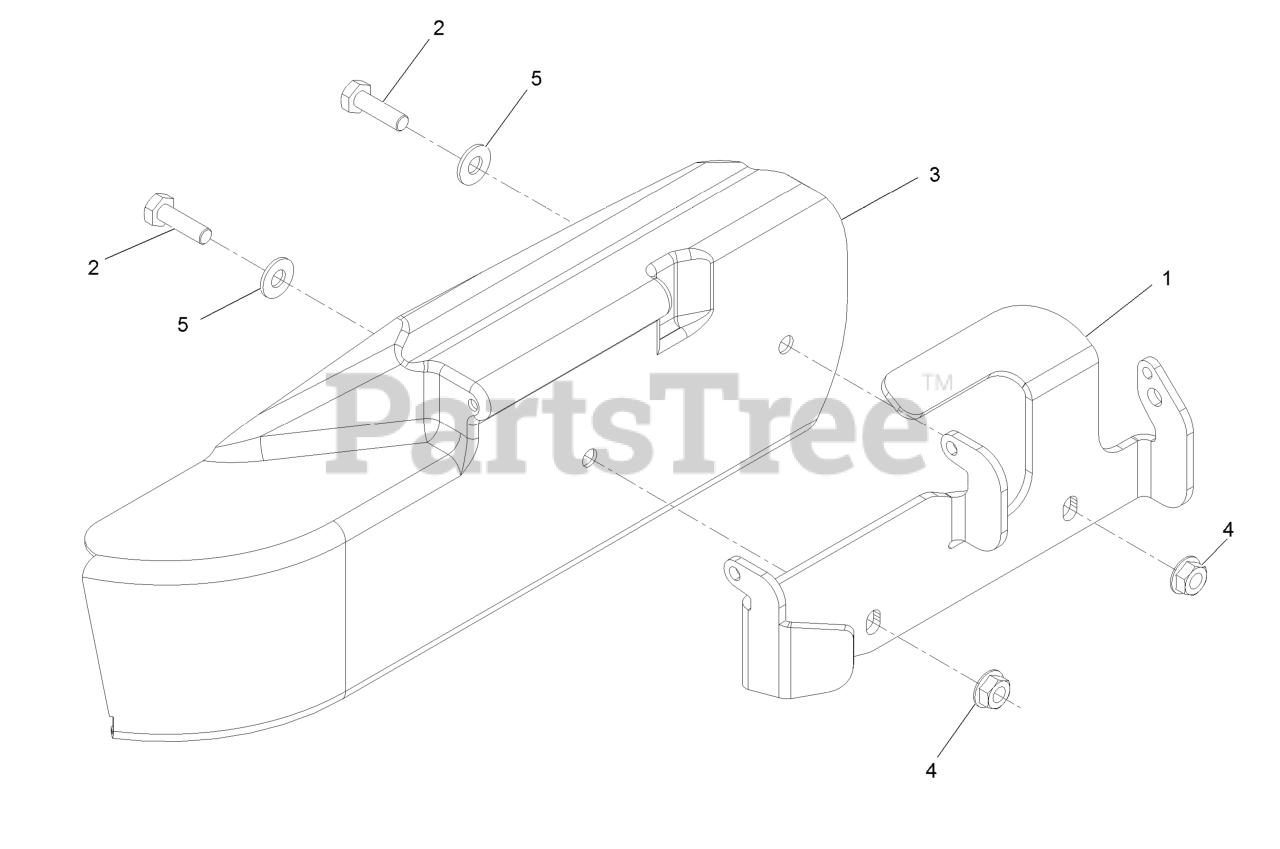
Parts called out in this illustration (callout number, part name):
1	Bracket-Deflector, Side
2	Screw-HH 1/4-20 X 7/8 SS
3	Deflector-Side
4	Nut-Hex Flg
5	Washer-Flat
